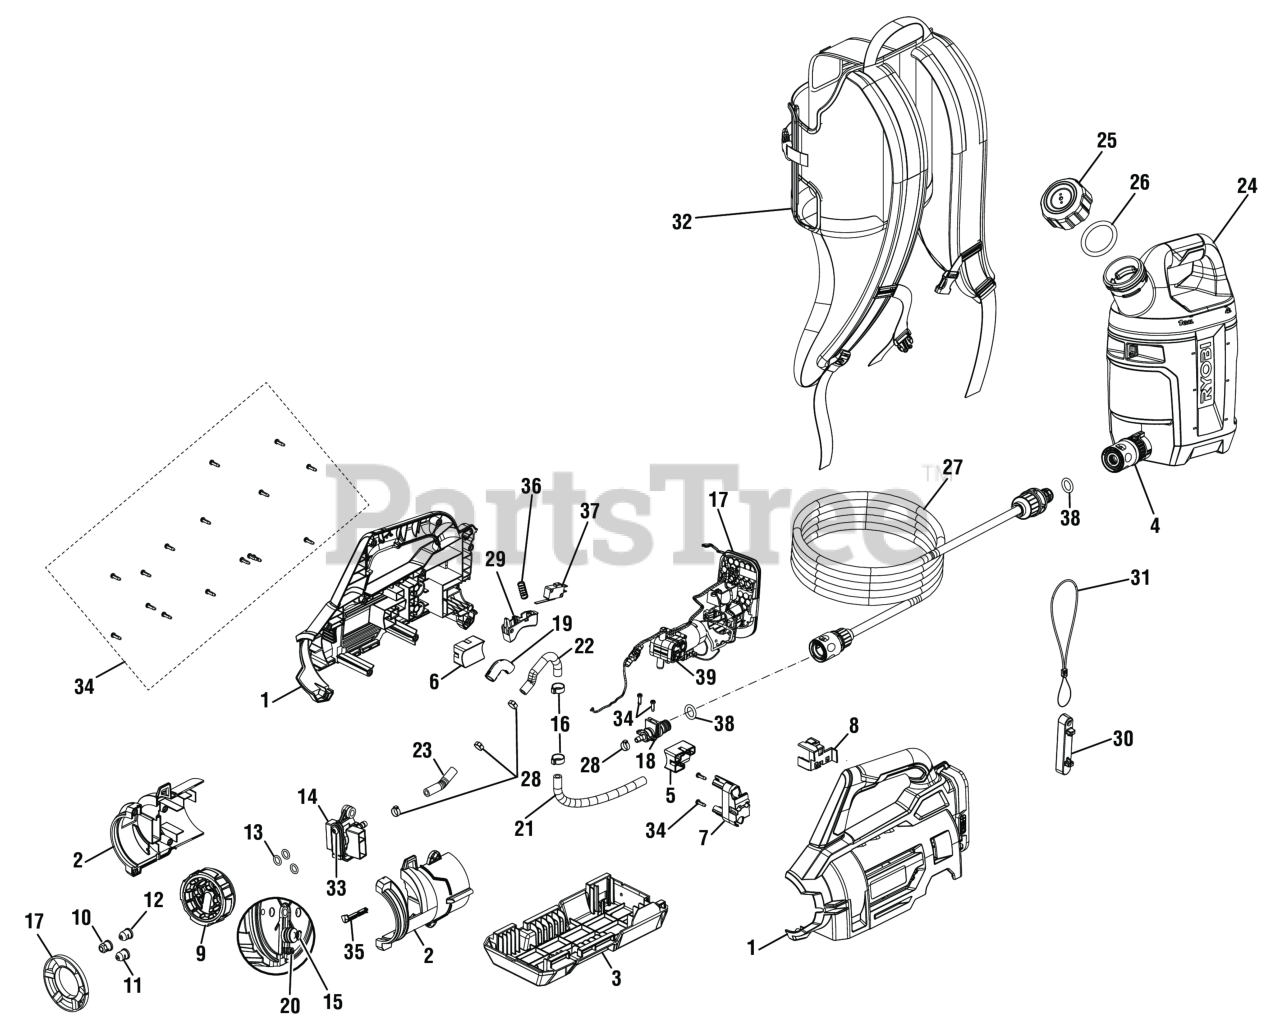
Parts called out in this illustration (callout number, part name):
1	Housing Assembly (Inc. Labels)
2	Outlet Tube Assembly (Inc. Label)
3	Bottom Plate Assembly (Inc. Label)
4	Shut-off Valve
5	Left Motor Support
6	Right Motor Support
7	Base for Pump
9	Nozzle Dial Assembly (Inc. Labels)
10	Low Spray Nozzle Assembly
11	Medium Spray Nozzle Assembly
12	High Spray Nozzle Assembly
14	Nozzle Body Assembly
15	Piston Seal Assembly
17	Motor & Battery Foot Assembly
18	Male Quick Connect
19	Pipe Shroud Assembly
20	Ball and Spring Assembly
21	Tube (Pump Inlet)
22	Tube (Pump Outlet)
23	Tube (Barb Nozzle)
24	Tank Assembly
27	Hose Assembly
29	Switch Trigger
30	Nozzle Wrench
32	Tank Holster
33	Screw (M5)
34	Screw (M4 x 14 mm, T15 Torx Pan Hd.))
35	Wire Cover
36	Compression Spring
38	O-Ring (ID11.3 x CS2.5)
39	Motor & Pump Assembly
